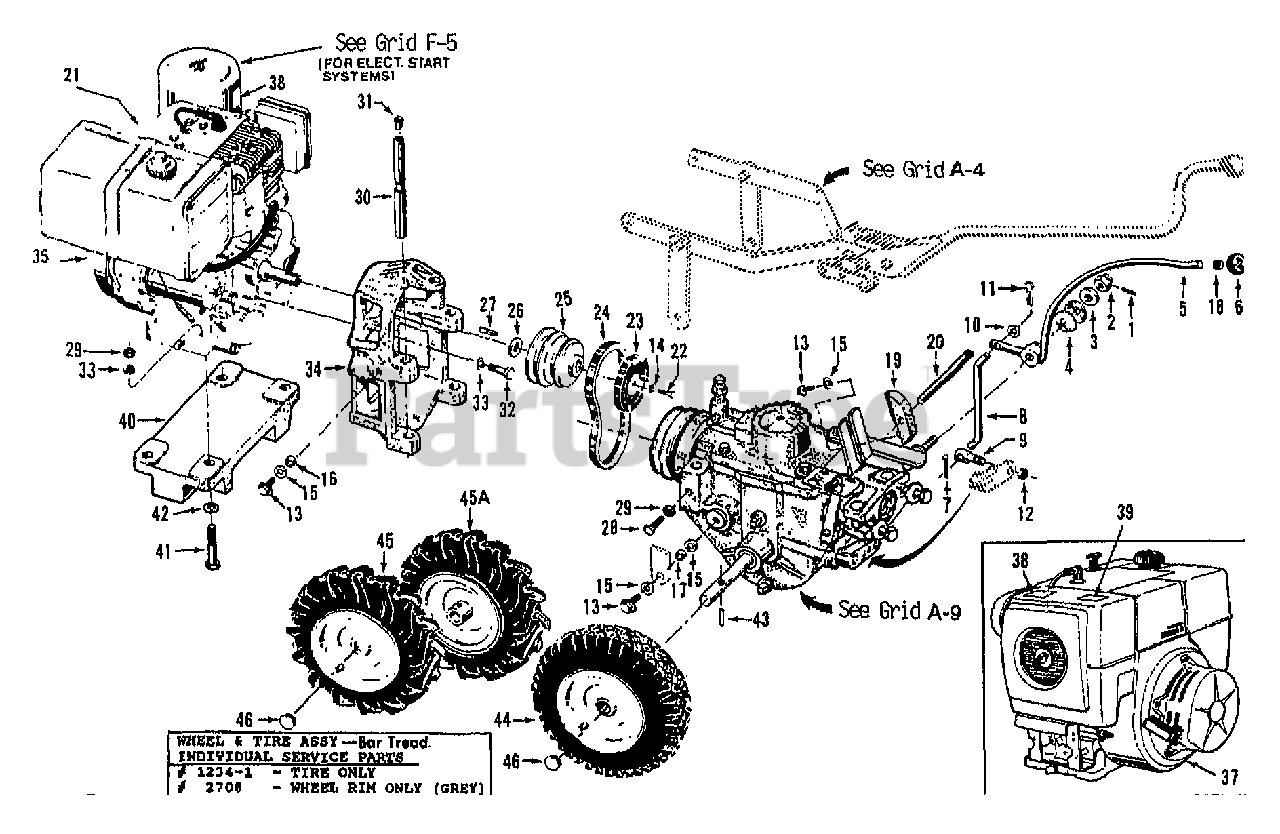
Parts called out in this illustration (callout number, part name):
1	PIN-SPRING .125 X 1
2	NUT-HEX 1/2-20 (CALL TECH SERV. DEPT. FOR TIGHTENING INSTRUCTIONS)
3	WASHER-# SHOULDER ZP (SHOULDER FACES DISC WASHERS)
4	WASHER-# 1.97X1X.118 (CONCAVE SURFACES FACE EACH OTHER)
5	LVR-W/KNOB (WHEEL SPEED)
6	KNOB-WHEEL SPEED HORSE (INCL. #18 & PLASTIC DECAL INLAY)
7	PIN-COTTER .094X1.0
8	ROD-CONNECTING
9	SWIVEL
10	WASHER-FLAT 5/16 SAE
11	PIN-CLIP .08
12	NUT-H/LK 5/16-18
13	SCR-HFLK 3/8-16X1.00 ZP
14	WASHER-LK .375 @ DEPL
15	WASHER-FLAT 3/8 SAE
16	BUSHING-.5X.375X.325
17	BUSHING-.5X.375X.3
18	RING-TOLERANCE .5325 ID
19	KIT-ADJ BLOCK 4 SP (INCL. # 13,15, & 20)
20	BAR-ADJUST
21	DECAL-STARTING STABIL
22	SCR-HH 3/8-24X1.5 G5
23	KIT-ADJ BLOCK/REV DISC (INCL. #19)
23	DISC-REV
24	BELT-V (NO SUBSITUTES RECOMMENDED DUE TO EXTRA STRENGTH REQUIRED)
25	PULLEY-ENG MACH (POWER TAKE OFF)
26	SHIM-1.0X.7656X.062
26	SHIM-1.0X.7656X.031
27	KEY-.188 SQ X 2.33
28	SCR-HH 5/16-18X1.0 G5 ZP
29	NUT-HEX 5/16-18 ZP
30	BAR-ENG MTG W/CAP PLUG
31	PLUG-CAP (RED)
32	BOLT-HH 5/16-24X1.125 G5 ZP
33	WASHER-LK .312 ZP
34	MOUNT-MOTOR HSE OPC PNT
35	7HP B&S RECOIL START MOD. #171432, TYPE #0529.
35	7HP B&S ELEC. START MOD. #171437, TYPE #0530.
36	8HP B&S RECOIL START MOD. #195432, TYPE #0857.
36	8HP B&S ELEC. START MOD. #195437, TYPE #0858.
37	8HP KOHLER RECOIL START. MOD. #M8T SPEC. #PS-301608.
37	8HP KOHLER ELEC. START. MOD. #M8ST SPEC. #PS-301609.
38	DECAL-HOT SURFACE
39	DECAL-STABIL STARTING
40	WEIGHT-ENG ECONO PNT
41	SCR-HH 5/16-18X2.25 G5ZP
42	SPACER-.88X.385X.09 ZP
43	PIN-SPIROL .313 X 1.5
44	ASSM-STD TIRE
45	TIRE-LT BT GARDEN TRAC (WHITE)
45	ASSM-TIRE&WHEEL LH GRAY
45A	TIRE-RT BT GARDEN TRAC (WHITE)
45A	ASSM-TIRE&WHEEL RH GRAY
46	CAP-HUB BLK PLASTIC
